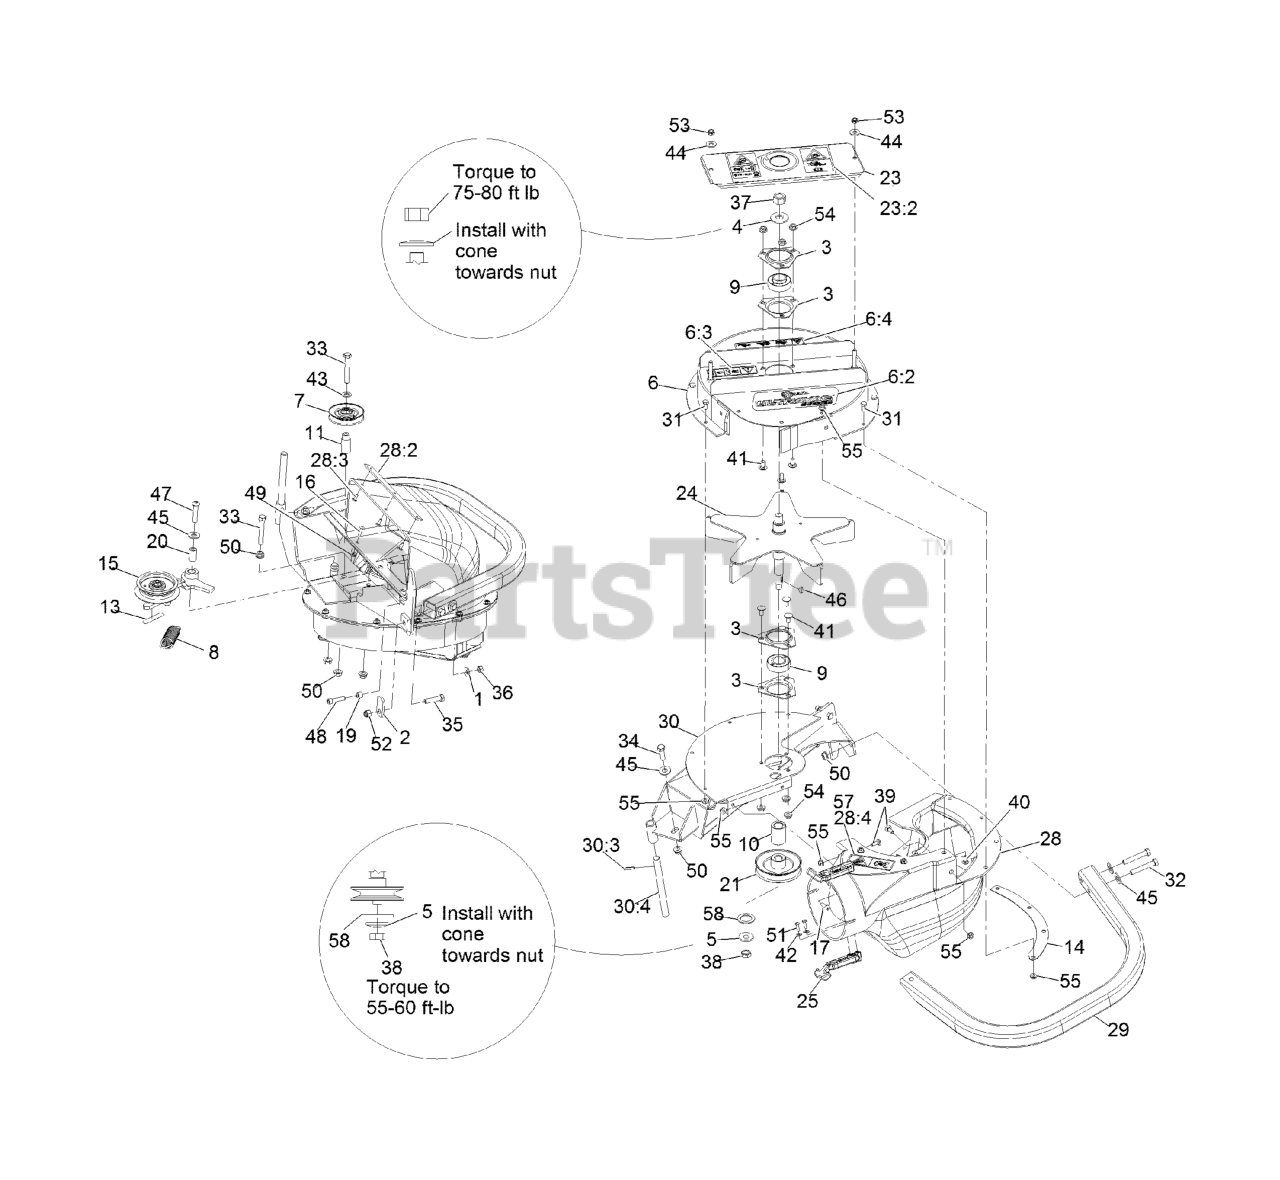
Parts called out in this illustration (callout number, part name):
1	WASHER-SPRING
2	LATCH-CATCHER, GRASS
3	HOUSING-FLANGE
4	WASHER-SPRING
5	WASHER-SPRING
6	ASM-UPPER HOUSING SMALL
6:2	DECAL-ULTRAVAC S-SERIES
6:3	DECAL-COVER, MISSING
6:4	DECAL-WARNING WEIGHT
7	IDLER-INSIDE
8	SPRING-IDLER
9	BEARING
13	DECAL-WARNING
14	PLATE-BACKING, BLOWER
15	ASM, Idler
16	SCREW-HEAD, TRUSS
19	BUSHING, LOCATOR
20	BUSHING-PIVOT, IDLER
21	SHEAVE-BLOWER
23	ASM, BEARING COVER
23:2	DECAL-WARNING BLOWER
24	IMPELLER
25	LATCH-RUBBER
28	ASM,BLOWER CHUTE LHP
28:2	PLATE-REINFORCEMENT
28:3	RIVET-BLIND
28:4	Decal-Blower-Impeller Hazard
30	WELD, FRAME SM BLOWER
30:3	PIN-ROLL
30:4	SHAFT-CATCHER, GRASS
31	SCREW-HH
32	SCREW-HH
33	SCREW-HH
34	SCREW-HH
35	SCREW-HH
36	NUT-HEX
37	NUT-HEX
38	NUT-JAM
39	BOLT-CARR
40	SCREW-CARR
41	SCREW-CARR
42	WASHER-FLAT
43	WASHER-FLAT
44	WASHER-FLAT
45	WASHER-FLAT
46	KEY-WOODRUFF
47	SCREW-HSBH
48	SCREW-HSH
50	NUT-HHF, WHIZ
51	SCREW-PPH
52	NUT-LOCK, NI
53	NUT-LOCK, NI
57	Decal-Blower-Impeller Hazard
58	WASHER-SPACER
